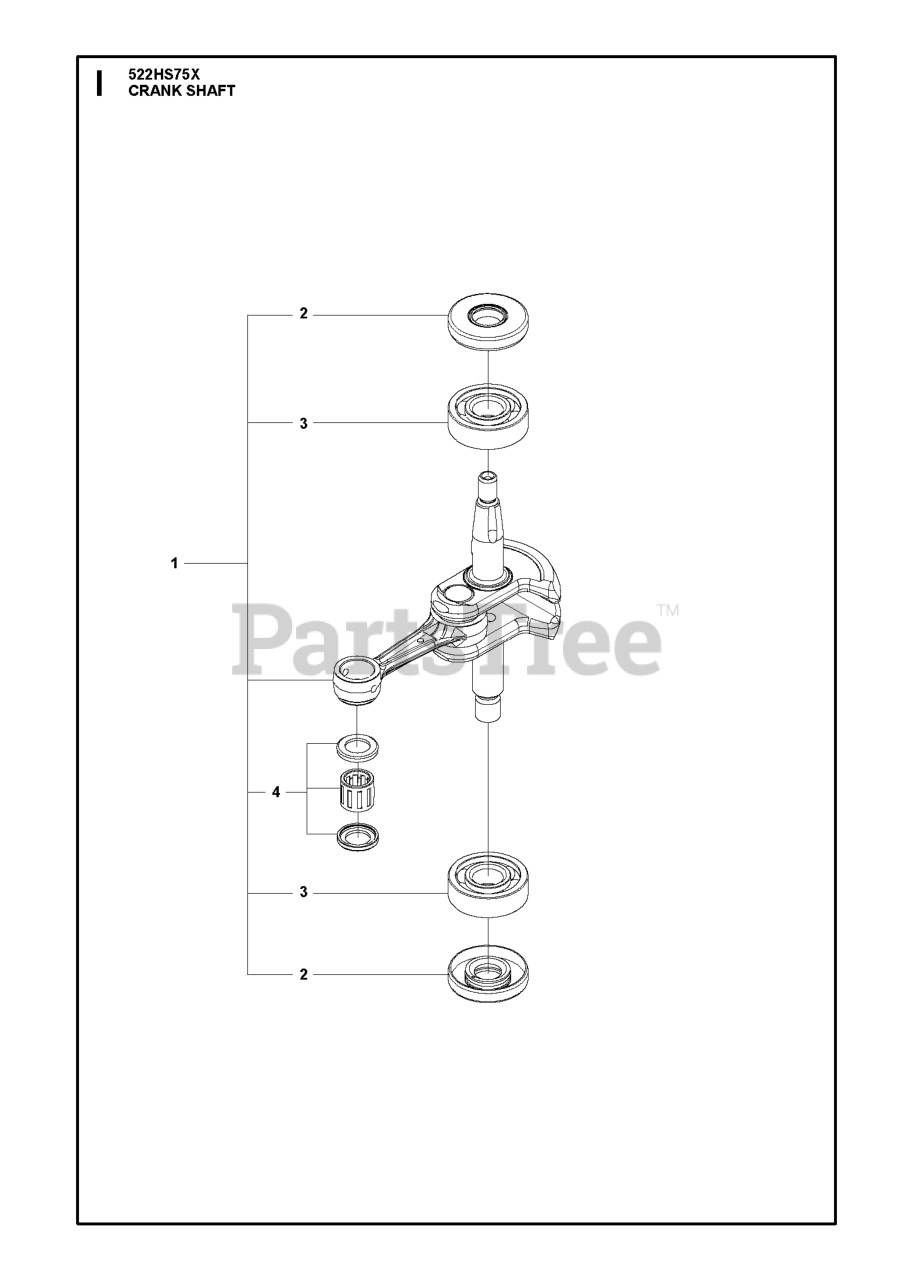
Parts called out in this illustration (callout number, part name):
1	CRANKSHAFT KIT
2	SEALING RING
3	BALL BEARING
4	NEEDLE BEARING
